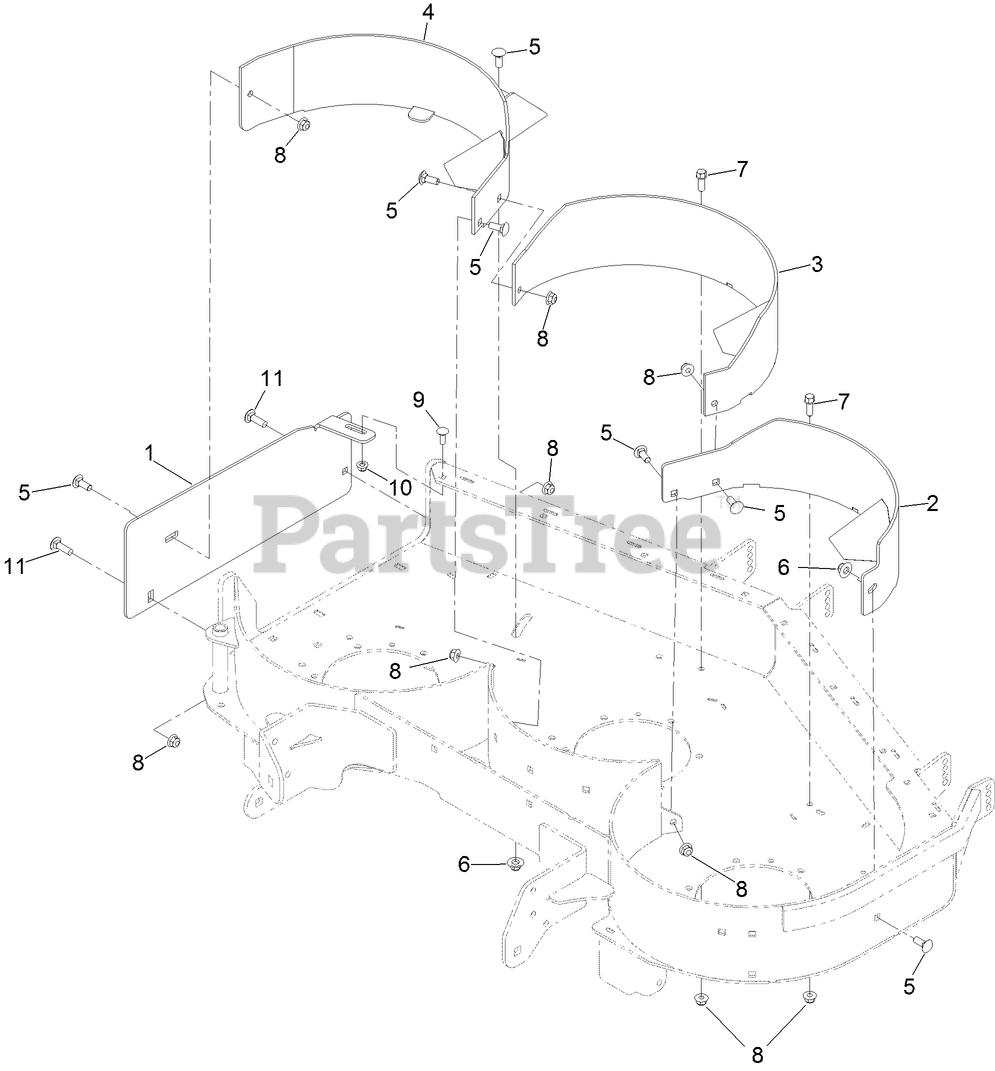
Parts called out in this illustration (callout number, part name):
1	PLATE-COVER, DISCHARGE
2	BAFFLE-LH
3	BAFFLE-CENTER
4	RH BAFFLE ASM
5	BOLT-CARR
6	NUT-FLANGE, NI
8	NUT-HF, NI
9	SCREW-CARR
10	NUT-HF, NI
11	BOLT-CARR
